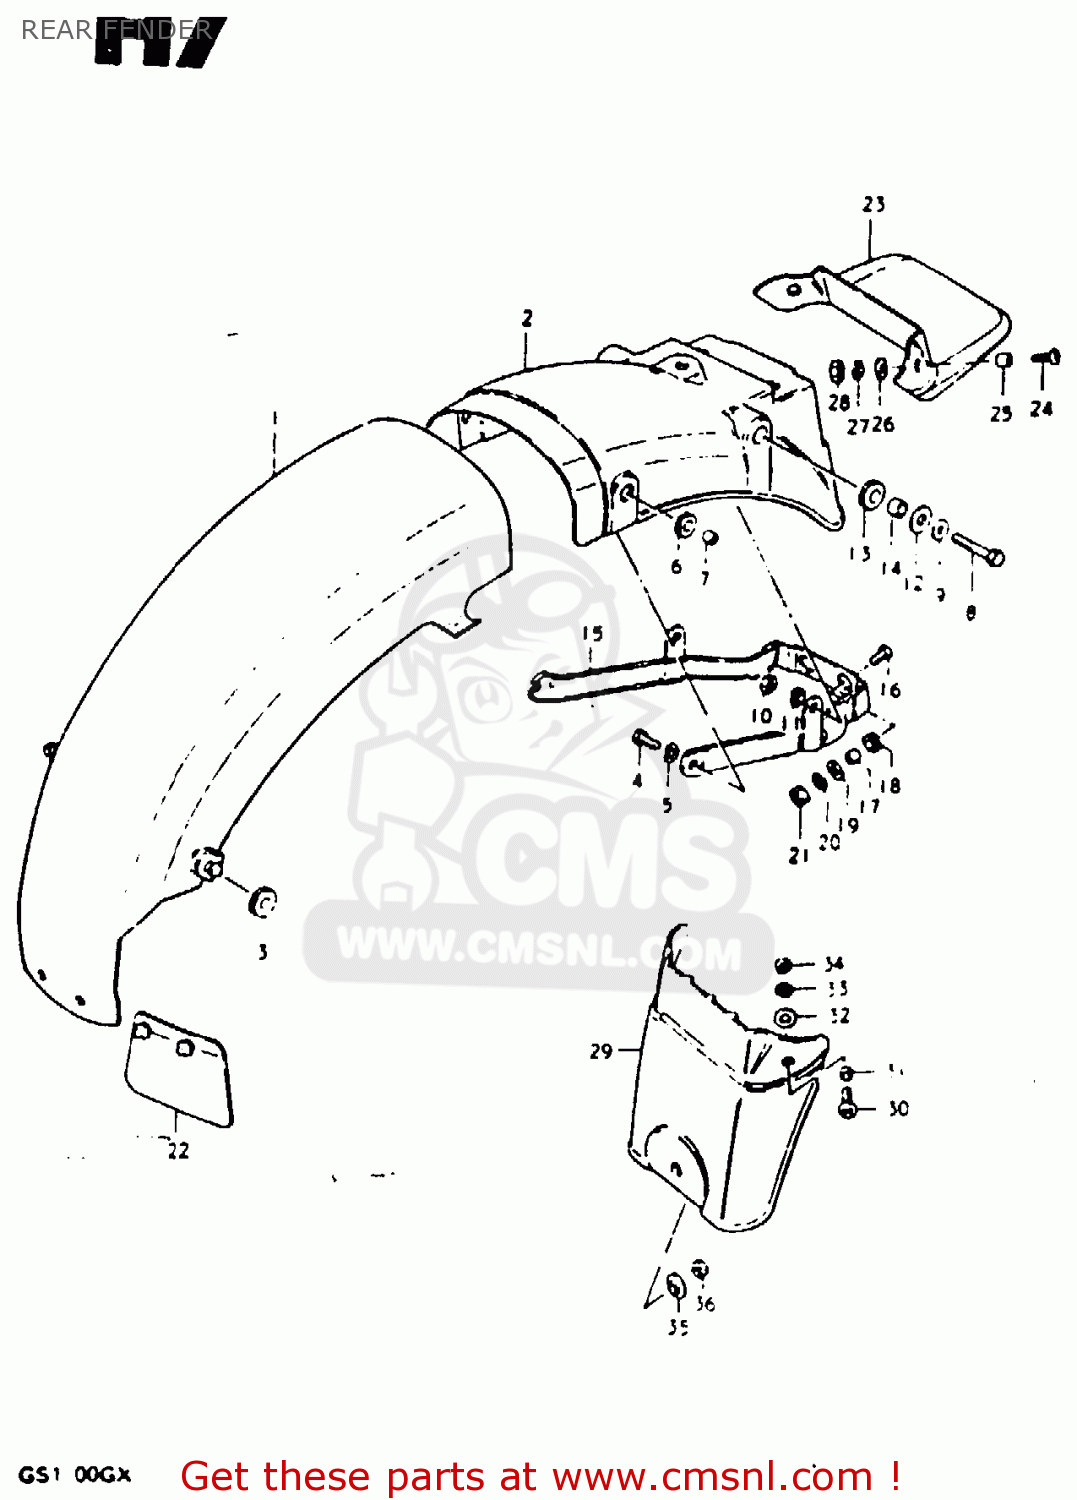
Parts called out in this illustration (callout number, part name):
1	FENDER,REAR
2	BODY,RR FENDER RR
3	CUSHION
4	BOLT
5	LOCK WASHER
6	CUSHION
7	SPACER(6.1X9X7.5)
8	BOLT
9	WASHER
10	NUT
11	LOCK WASHER
12	WASHER(8.5X26X1.2)
13	CUSHION
14	SPACER (8.2X12X7.5)
15	REINFORCEMENT,REAR FENDER
16	SCREW
17	SPACER (6.1X9X9)
18	CUSHION
19	WASHER(6,5X22X1.6)
20	LOCK WASHER
21	NUT
22	GUIDE,RR FENDER MUD
23	EXTENSION,REAR FENDER
24	SCREW (6X15)
25	SPACER(6.2X8.3X5.7)
26	WASHER(6.5X18X1)
27	LOCK WASHER
28	NUT
29	EXTENSION,REAR FENDER
30	SCREW (6X15)
31	SPACER(6.2X8.3X5.7)
32	WASHER(6.5X18X1)
33	LOCK WASHER
34	NUT
35	SPACER
36	NUT
